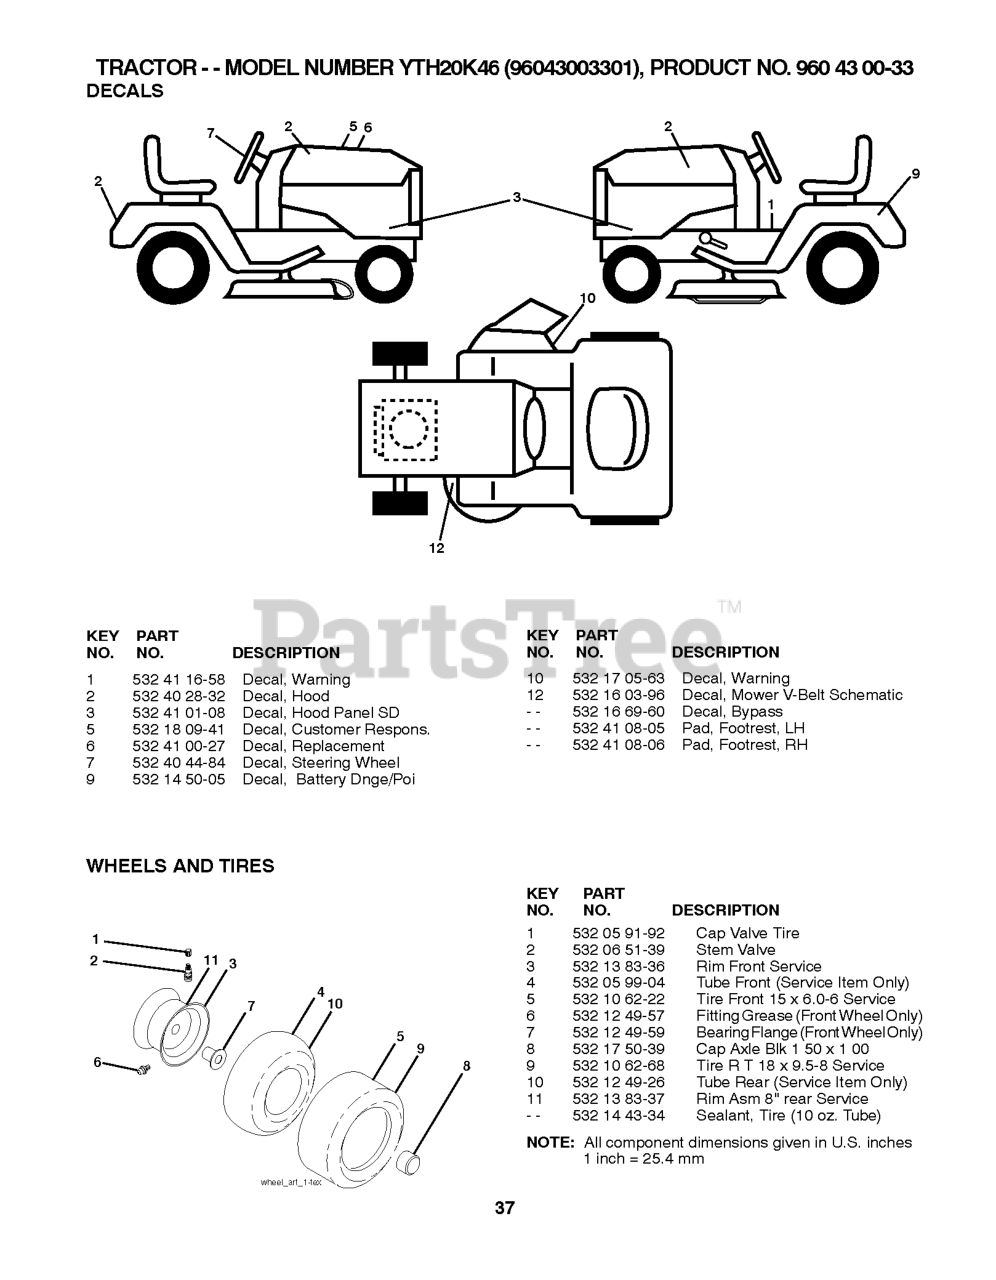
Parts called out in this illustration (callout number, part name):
2	VALVE STEM LT
3	RIM ASM 6" FRONT SILVER
4	TUBE.5.3/4.5/6
5	TIRE HEAVY DUTY
6	FITTING LT
7	BEARING T
8	CAP, AXLE BLK
9	TIRE HEAVY DUTY
10	TUBE
11	RIM ASM 8" REAR SILVER
